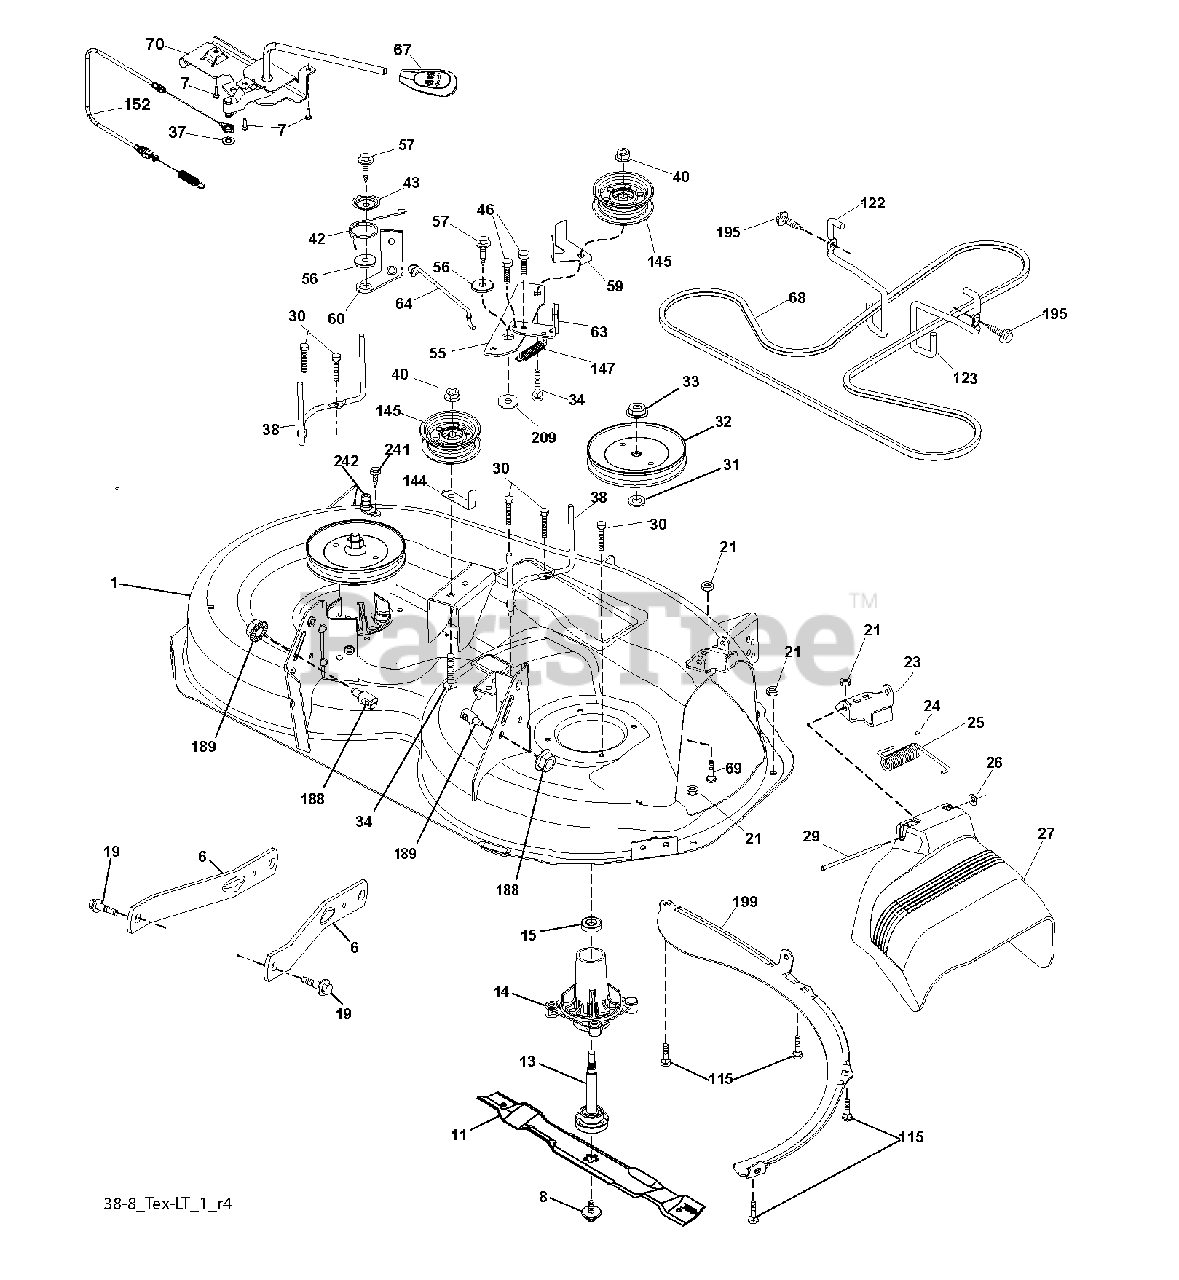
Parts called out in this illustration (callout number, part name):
6	ARM.SUSPENSION.MOWER.R
7	SCREW.#10 X 0.750.BOS THREAD
8	BOLT.WASHER.ASM.7/16-2
13	SHAFT.ASM.MDRL.N/GREASE.38
14	HOUSING MANDREL
15	BEARING
19	BOLT.SHOULDER
23	BRKT.DEFLECTOR.38"2005
24	CAP-SLEEVE LT
25	SPRING.TORSION.DEFLECT
26	NUT PUSH M
29	HINGE ROD
30	SCREW, WASHER HEAD
33	NUT.FLANGE.LOCK.TOP
37	WASHER
46	SCREW 1/4-20X5/8
55	IDLER.ARM
56	SPACER.RETAINER
57	SCREW 3/8-16X1
59	GUARD
69	BOLT
115	BOLT
145	PULLEY.IDLER.48"PRIMARY
147	SPRING RETURN
188	STUD.FASTNER.W/D.ANTI-
189	NUT LOCK HEX FLANGE 5/16-18
195	SCREW, 3/8-16X3/4
242	PORT.WASHOUT
